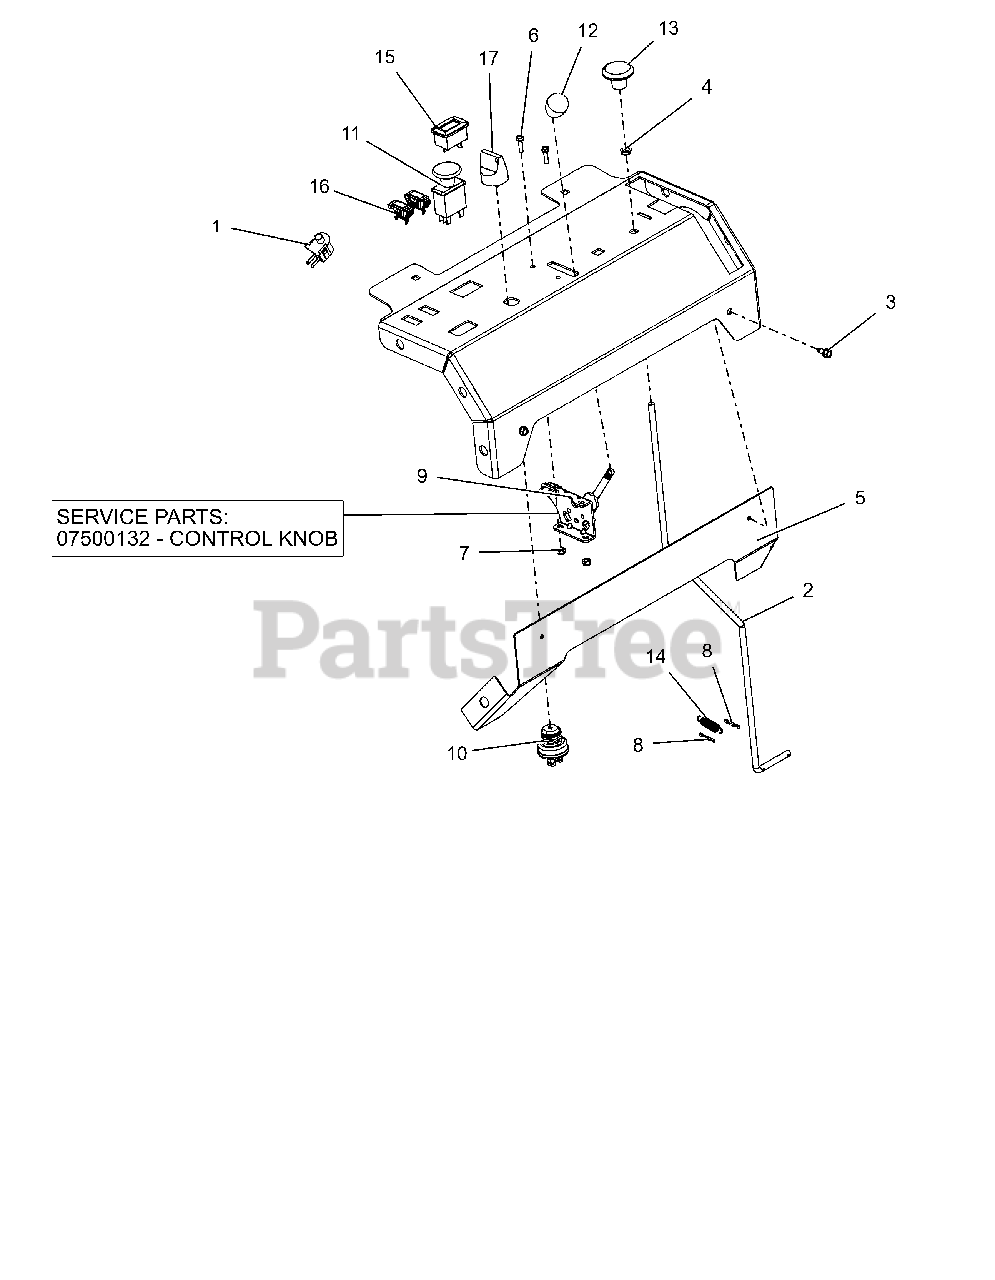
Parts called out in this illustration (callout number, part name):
1	SWITCH- SNAP MTG N.O.
2	WIREFORM, TRAILER LOCK
3	SCR-TAP .25-20X.50 HWH TR YWZ
4	BUSHING, POLYLINER-.38 SNAPIN
5	PLATE, FRONT BACKER
6	@SCR-MCH 10-24X.75 HWH YWZC
7	@NUT-LK-NYL 10-24 W/INSRT YWZC
8	PIN-HAIR, ENDRIES #25 YWZC
9	CABLE, PRO-CONTROL
9	KNOB-CONTROL-BLACK .38-16X.50
10	SWITCH, IGNITION
11	SWITCH, CLUTCH
12	KNOB-CONTROL-BLACK .38-16X.50
13	KNOB, PUSH-PULL .312-18
14	SG-TENS .048X.44X1.75 WLD 9
15	METER, HOUR W/MAINTENANCE
16	LIGHT,INDICATOR
17	KEY, W/ SHIELD
